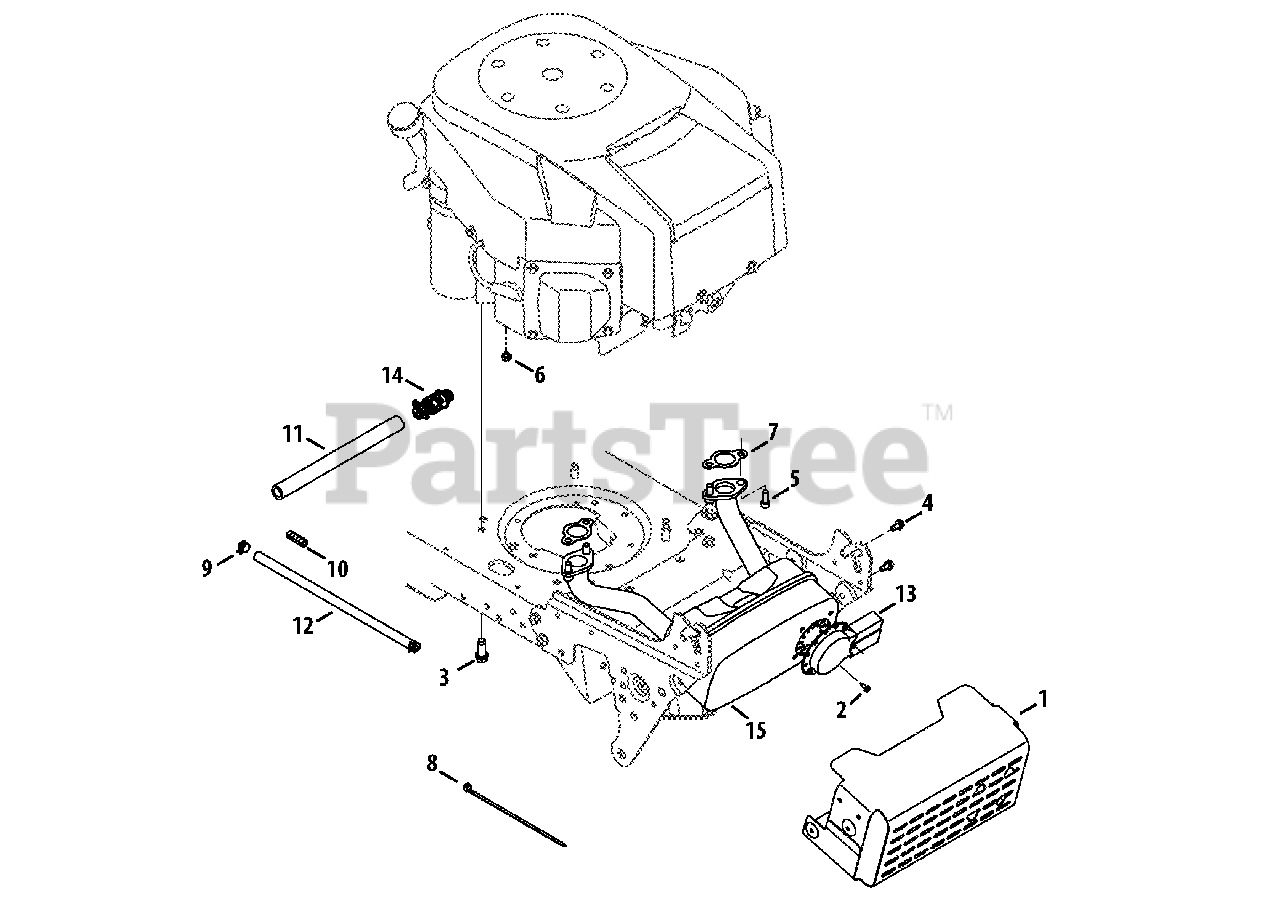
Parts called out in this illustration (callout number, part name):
1	Shield Ass’y, Muffler
2	Screw, Ab, #8-18, 0.500,
3	Screw, Self-tapping, 3/8-16, 1.000,
4	Screw, Self-tapping, 1/4-20, 0.500,
5	Screw, Socket Head, 5/16-18, .750
6	Nut, Sems, 1/4-20
7	Gasket, Exhaust
8	Cable, Tie, 3/16 x .05 x 7.4
9	Clamp, Hose, .490 Dia.
11	Hose, Extension, Oil Drain
12	Hose, Fuel, Low Permeation, 1/4
13	Deflector, Muffler, Long
15	Muffler, Twin, Kohler
